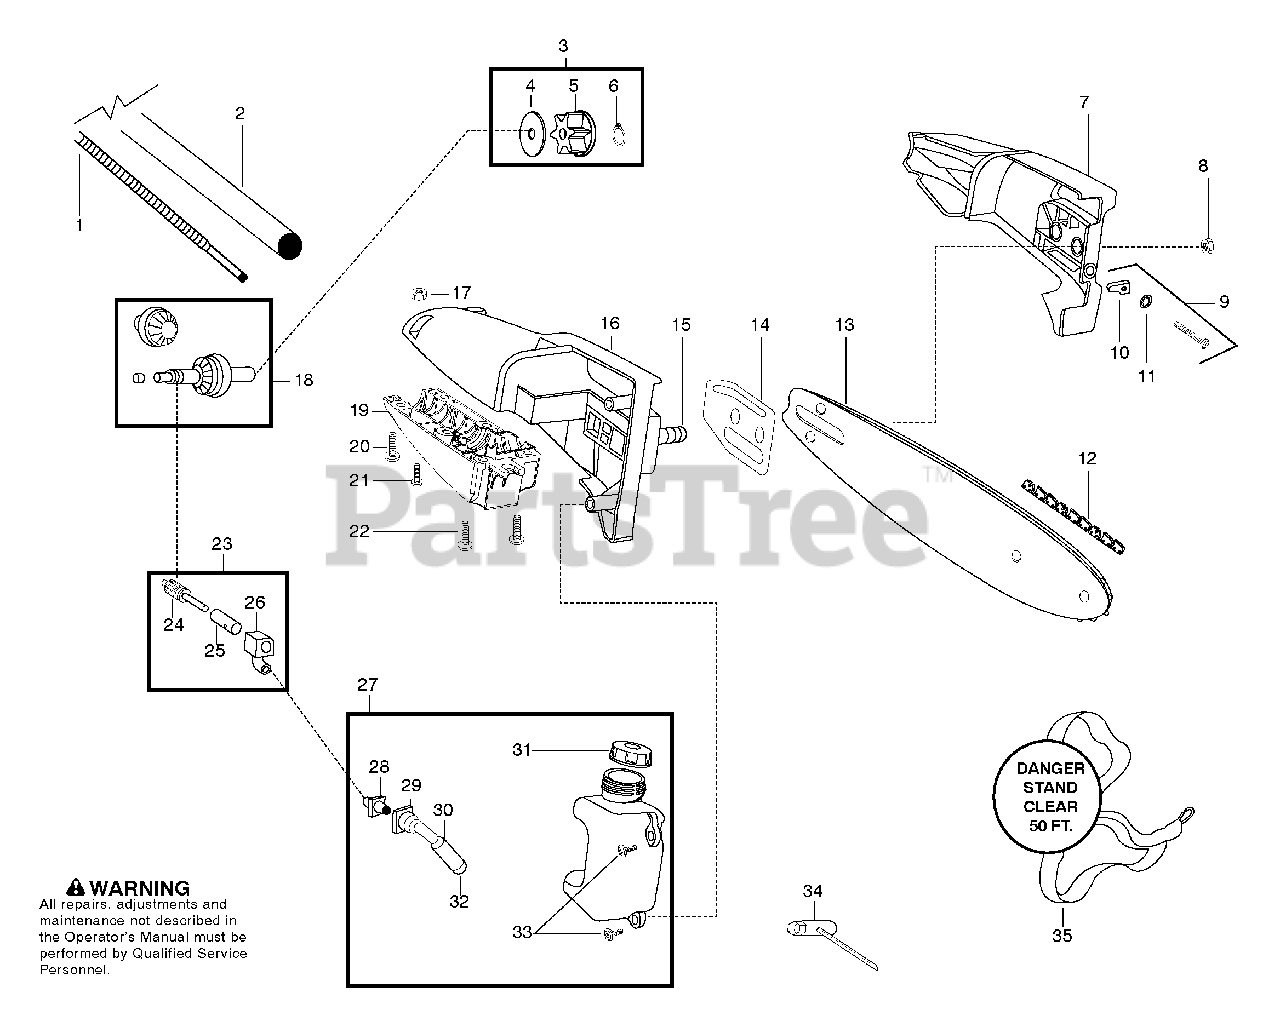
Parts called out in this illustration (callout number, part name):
1	Flexshaft - lower
2	Assy. - Lower Driveshaft
3	Kit - Sprocket Assy.
6	Retainer - Sprocket
7	Assy - Bar Clamp
8	Nut - Bar Mounting
9	Kit - Bar Adjust
10	Pin - Bar Adjust
11	Retainer - Bar Adjust
12	Chain - 8"
14	Plate - Bar Pad
15	Bolt - Bar
16	Housing - Upper
18	Kit - Gear Assy.
19	Housing - Lower
21	Screw - Alignment
23	Kit - Oil Assy
24	Assy. - Gear Plunger
26	Block - Oil
27	Assy - Oil Tank
28	Fitting - Oil Line
29	Intake - Oil Line
30	Filter - Oil
32	Plug - Oil Filter
34	Wrench - Bar
35	Strap-Shoulder
